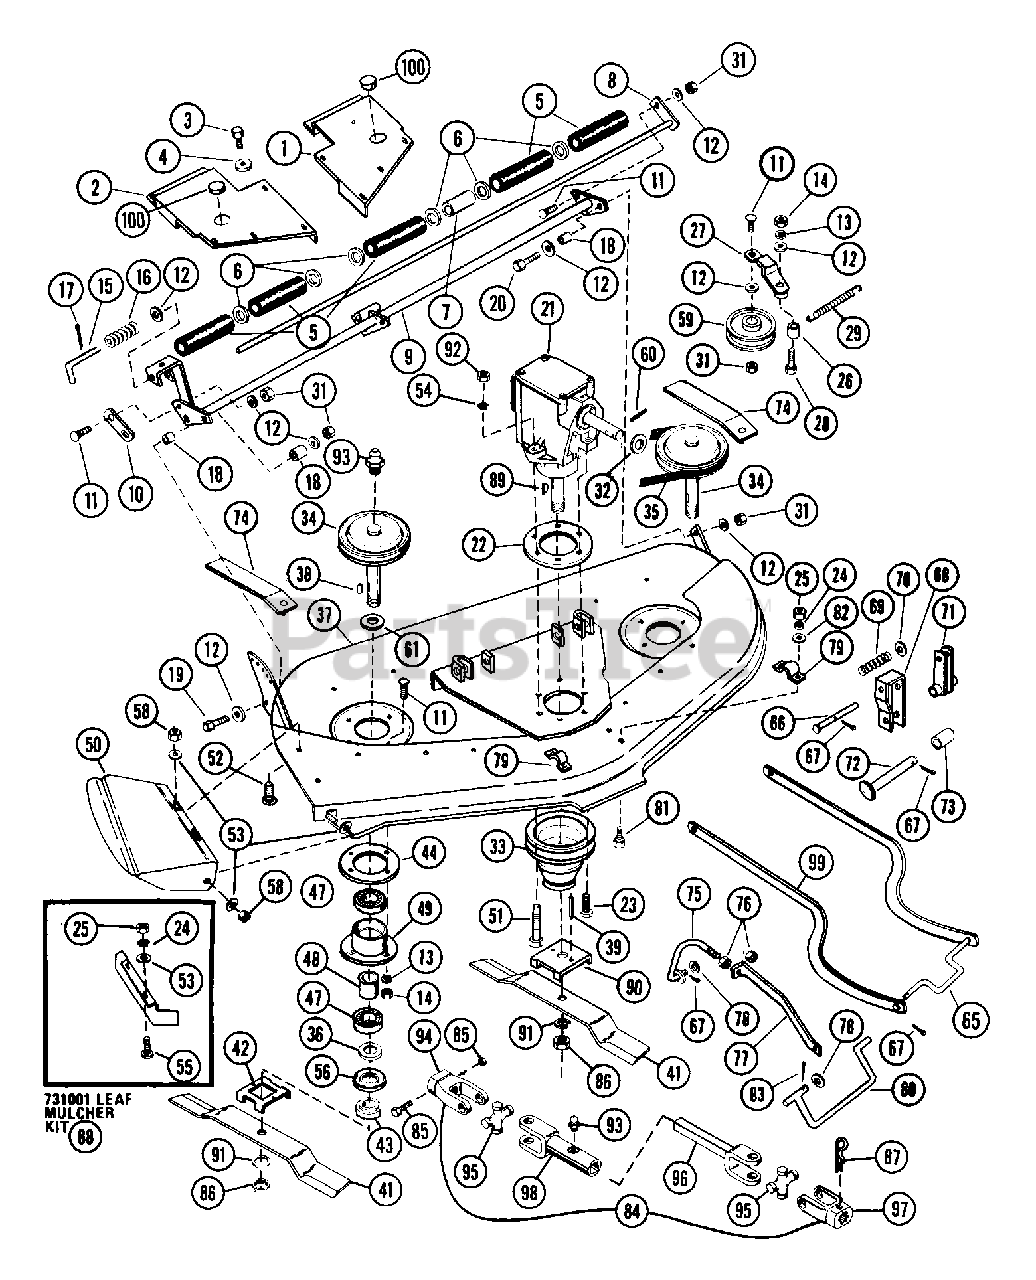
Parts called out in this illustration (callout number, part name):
1	SHIELD ASSEMBLY
2	R.H. BELT SHIELD
3	SCR-TAP .250-20X.50 HH F
4	WSHR-FL-STL.281X.62X.065 PL
6	WSHR-FL-STL.656X1.312X.095 PL
7	SPACER .692X.812X2.125
8	ROLLER SHAFT
9	ROLLER ADJUSTMENT
11	BLT-RDHDSQNK .38-16X1.0 PL
12	WSHR-FL-STL .438X1.0X.083 PL
13	WSHR-LK .375X.094 MED PL
14	NUT-HEX .375-16
16	SG-COMP .063X.63X1.75 WLD10
17	PIN-COTR .12X.75 PL
18	BSHG-SLV .377X.624X.235
19	BLT-HEX .38-16X1.25 PL GR 2
20	BLT-HEX .38-16X1.00 PL
21	MOWER GEAR CASE 42 IN
22	SHIM
23	SCR-TAP .312-18X1.0 THH PL TR
24	WSHR-LK .312X.097 PL HVY
25	NUT-HEX .312-18
26	BSHG-SLV .375X.625X.1.000
27	IDLER ARM
28	BLT-HEX .38-16X1.75 PL GR2
29	SG-TENS .125X.812X5.25 WLD 15
31	NUT-LK-JAM-CTR .375-16 PL
32	WSHR-FL-STL .754X1.000X.032
34	SPINDLE SHEAVE
35	V-BELT, HA-WRAPPED
36	WSHR-FL-STL .781X1.250X.059 PL
37	42 IN MOWER PAN ASSY
38	KEY-WDRF .188X.625X.25 SAE 61
39	PIN-GRV .188X.75 TP A
42	BLADE TRAY
43	RETAINER HUB
47	BRG-BALL .750X1.781X.61
48	SPACER .765X1.000X1.180
49	SPINDLE HOUSING
50	42 INCH CHUTE EXTENSION
51	BLT-HEX .31-18X1.25 PL GR5
52	BLT-RDHDSQNK .312-18X.62SHTPL
53	WSHR-FL-STL .38X.875X.083 PL
55	BLT-RDHDSQNK .31-18X1.0 SHT PL
56	BEARING SLINGER
58	NUT-LK .312-18 GR A PL
59	IDLER-FLAT 3.00 X .38 CLK.&CAP
60	PIN-ROLL .125X1.00
61	WSHR-FL-STL .755X1.375X.062 PL
65	MOWER HANGER
66	PIN-CLEV .498X4.50 YWZC
67	PIN-COTR .12X1.0 PL
68	SUPPORT CHANNEL
69	SG-COMP .62X.68X1.75
70	WSHR-FL-STL .531X1.062X.095 PL
72	PIN-CLEV .498X4.31 YWZC
73	SPACER .516X.749X.938
74	RAMP
75	ADJUSTING ROD
76	NUT .50-13 PL
78	WSHR-FL-STL.563X1.37X.109PL
80	SUPPORT SHAFT
81	BLT-RDHDSQNK .31-18X.75 GR5 PL
82	WSHR-FL-STL.344X.688X.065PL
83	PIN-COTR .25X1.50 ST PL
84	PTO SHAFT ASSEMBLY
84	PTO ASSEMBLY
85	SHEARBOLT & NUT ASSEMBLY
86	NUT-JAM .75-10 PL
87	PIN-HAIR INT .18X1.18X3.25 PL
88	ELEC START KIT-USA TEC #1133-1
89	KEY-WDRF .25X.750X.313 SAE91
90	BLADE TRAY
91	WSHR-LK .750X.188 MED PL
92	NUT-LK-TOP .312-18 GR C PL
93	SPIN DRIVE ZERK FITTING
95	JOURNAL CROSS & BEARING ASSEMB
96	YOKE AND SHAFT
98	SLIP YOKE
99	HANGER ARM
100	BUTTON PLUG 1.0
